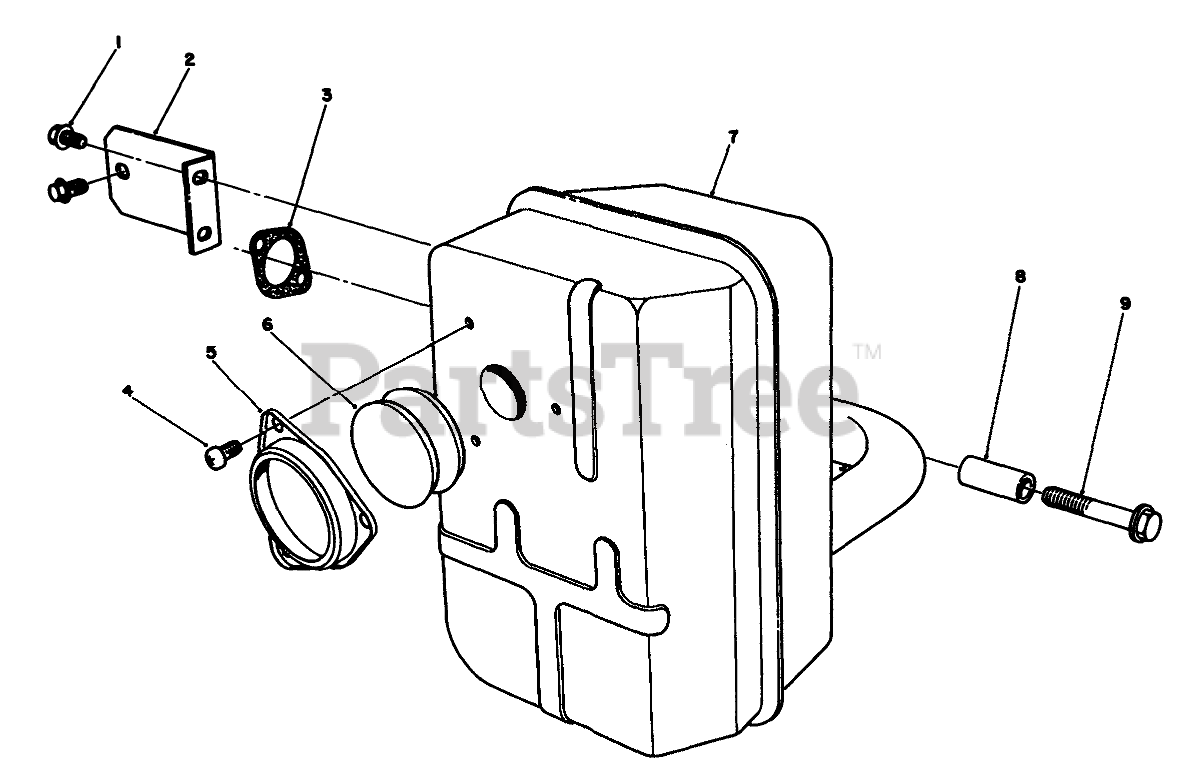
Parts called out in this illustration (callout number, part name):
1	Bolt-Flanged (8X12)
5	Cap
6	Arrester-Spark
7	Muffler ASM
9	Bolt-Flanged (8X45)
